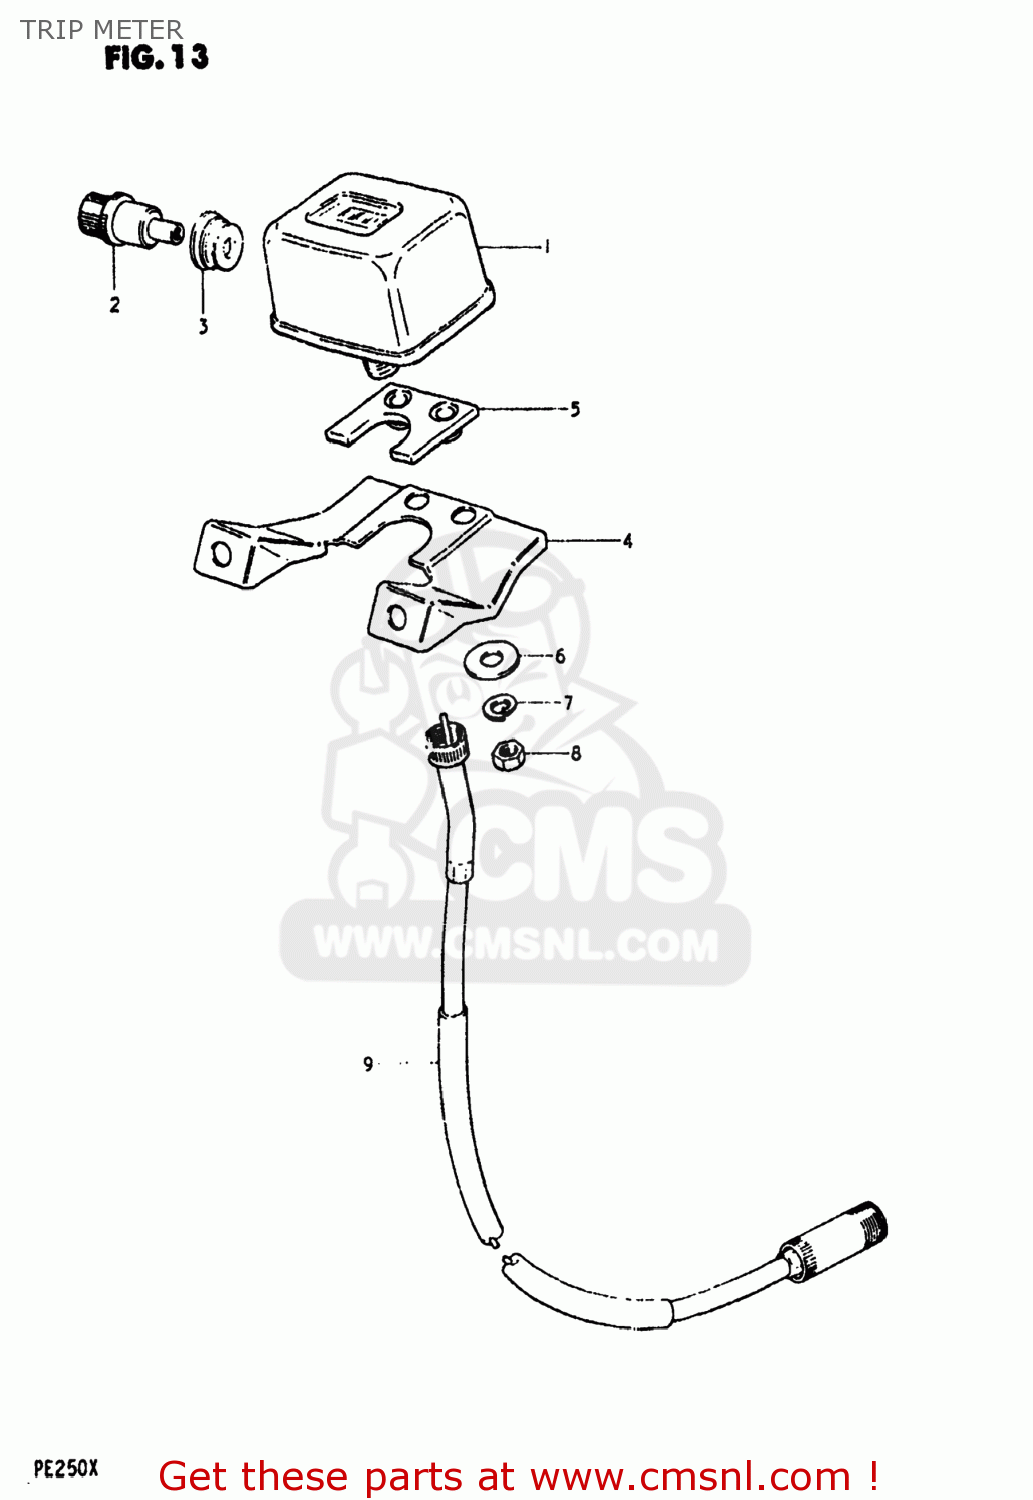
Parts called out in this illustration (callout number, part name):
1	TRIP METER
2	KNOB,TRIP METER
3	COVER,TRIPMETER KNOB
4	BRACKET,TRIPMETER
5	CUSHION,TRIPMETER
6	WASHER,METER
7	LOCK WASHER
8	NUT
9	CABLE ASSEMBLY,SPEEDOMETER
